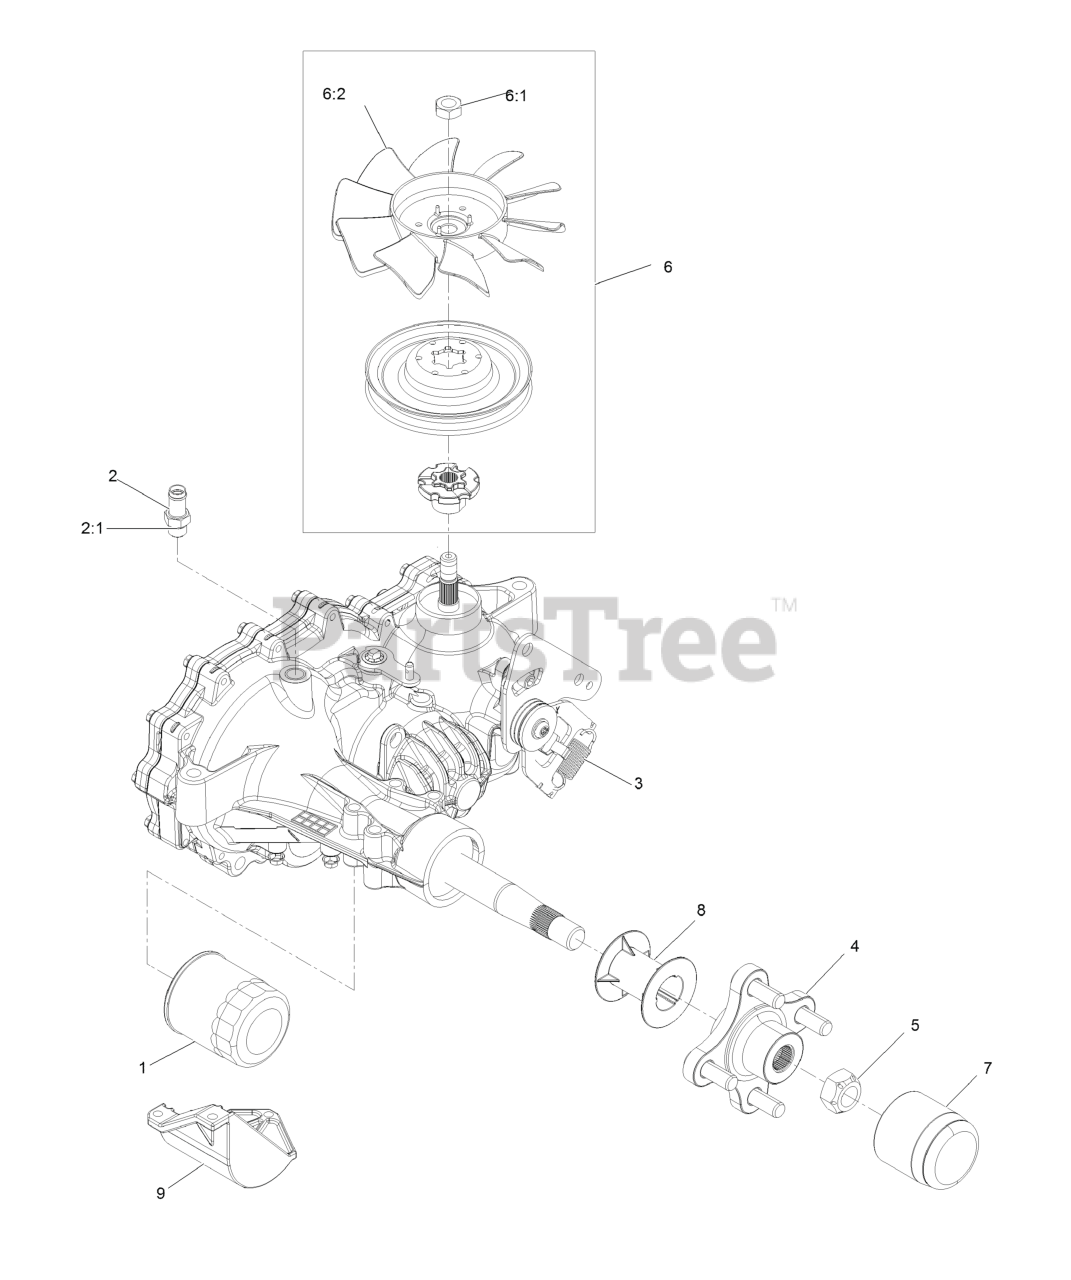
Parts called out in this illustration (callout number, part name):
1	ELEMENT-OIL FILTER, HYD
2	ADAPTER-STRAIGHT
2:1	O-RING
3	SPRING-EXTENSION
4	HUB-OFFSET
5	NUT-HUB
6	Fan And Pulley Kit
7	CAP-AXLE, LONG
8	TUBE-AXLE
9	GUARD-FILTER, RH
